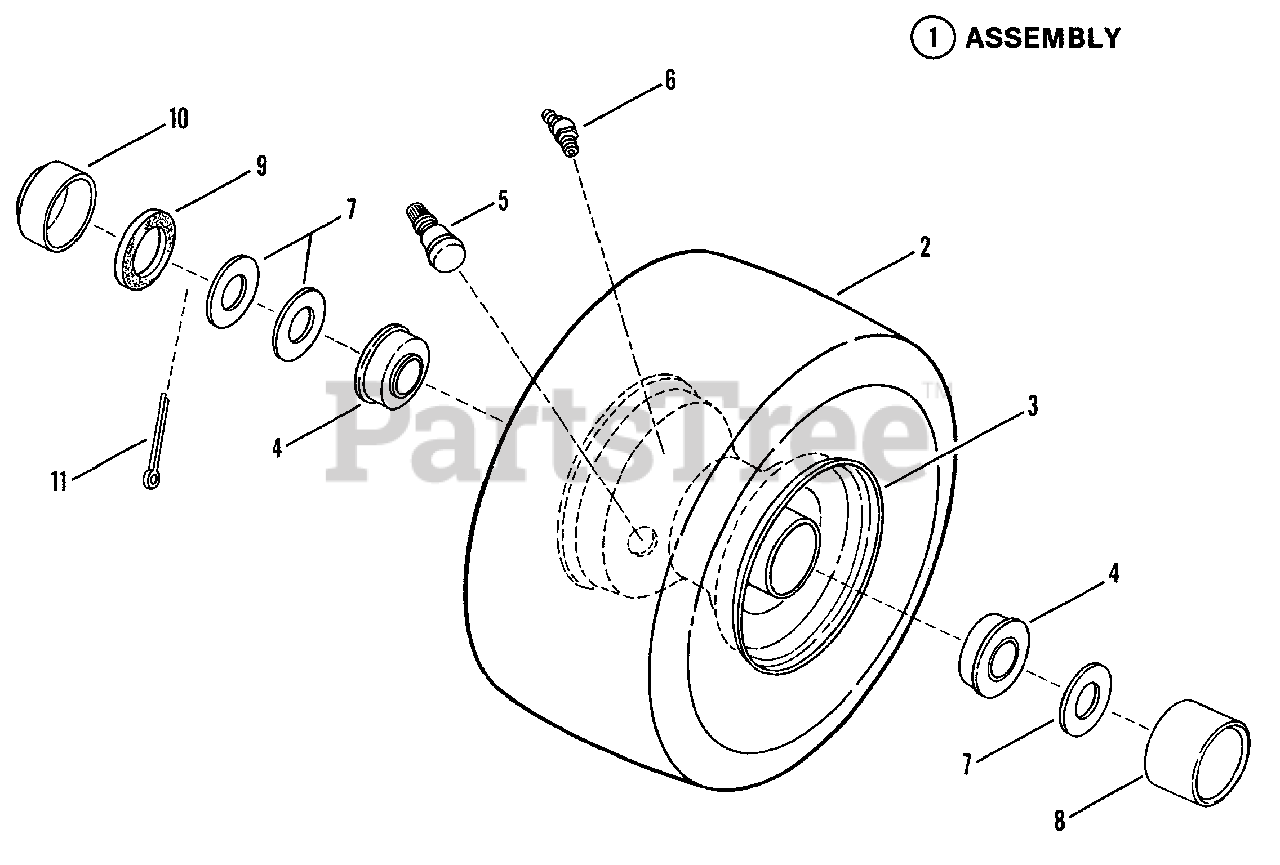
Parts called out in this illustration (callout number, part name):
1	ASSEMBLY, Front Tire & Rim, Complete, (Semi-Pneumatic)
2	TIRE, Pneumatic, 4.10/3.50x4
3	RIM, (For 4.10/3.50x4 Tire)
4	BEARING, Ball
5	VALVE, Air (Snap-in)
6	FITTING, Lube
7	WASHER
8	HUB-CAP
9	SEAL, Felt
10	CAP, Dust
11	COTTER-PIN
